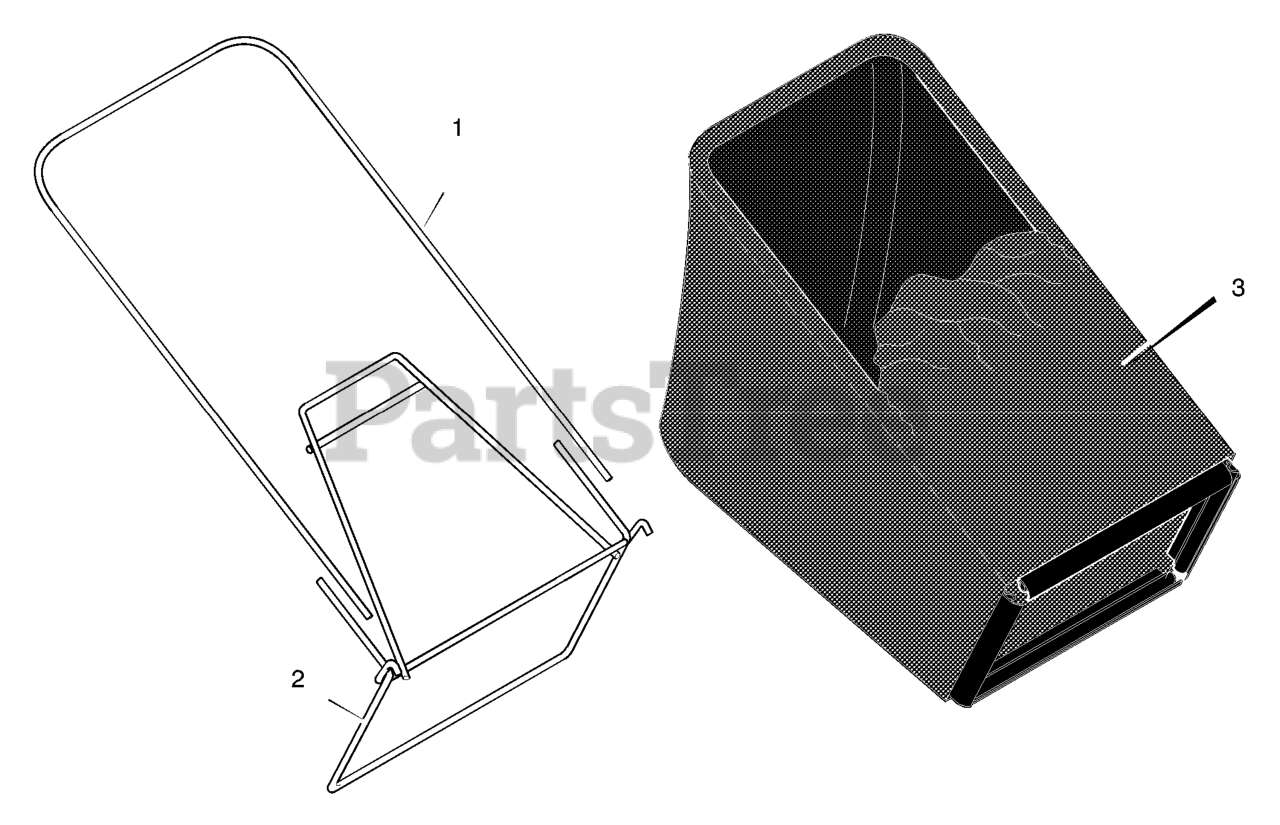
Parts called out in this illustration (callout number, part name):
1	Tube, Bag
2	Frame Assembly
3	Bag, Cloth - Black
